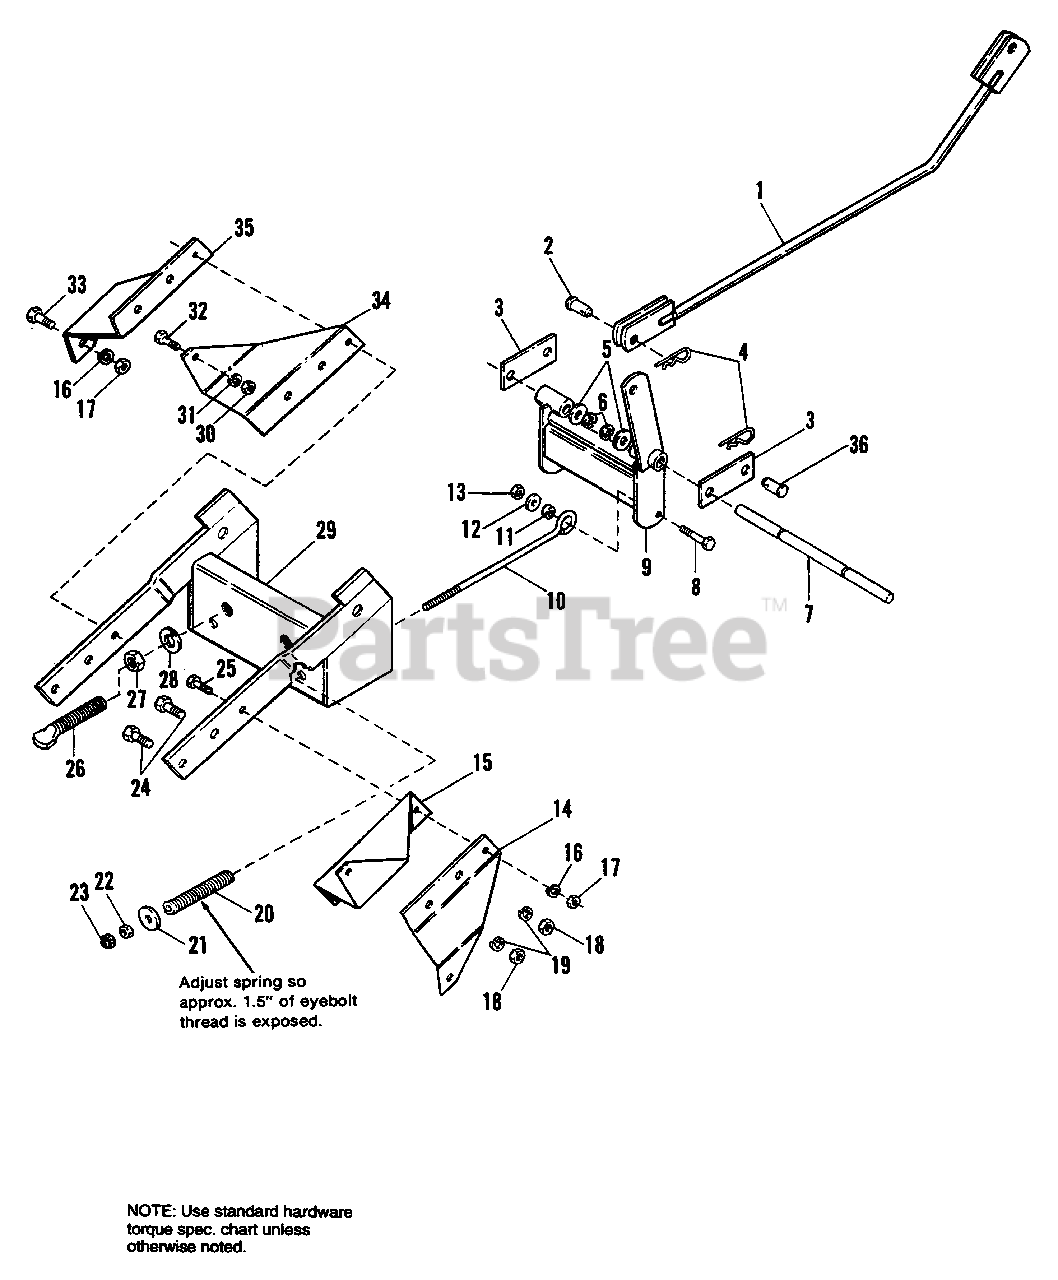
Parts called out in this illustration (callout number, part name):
1	LIFT ROD ASSY.
2	PIN, Clevis
4	CLIP, Hair Pin
5	WASHER, Plain, 41/64 x 1-1/4
6	RING, Retaining, 5/8
7	SHAFT, Inner
8	CAPSCREW, Hex Hd., 5/8-11 x 2
9	HITCH ASSY.
12	WASHER, Plain, 41/64 x 1-3/4
13	NUT, Hex, Centerlock, 5/8-11
14	BRACKET, Attaching, L.H., Lower
15	BRACKET, Attaching, L.H., Upper
16	LOCKWASHER, 3/8
17	NUT, 3/8-16
18	NUT, 7/16-14
19	LOCKWASHER, 7/16
20	SPRING, Compression
21	WASHER, 3/8 x 1-3/4 x 1/4
22	NUT, Hex, 3/8-16
23	NUT, Hex, Jam, 3/8-16
24	CAPSCREW, 7/16-14 x 1-1/4
25	CAPSCREW, 3/8-16 x 1-1/4
27	NUT, Hex, 3/4-10
28	LOCKWASHER, 3/4 Std.
29	HITCH ASSY., Blower
30	NUT, 1/2-13
31	LOCKWASHER, 1/2
32	CAPSCREW, Hex Hd., 1/2-13 x 1
33	CAPSCREW, Hex Hd., 3/8-16 x 1
34	BRACKET, Attaching, R.H., Upper
35	BRACKET, Attaching, R.H., Lower
36	PIN ASSY. (Flat Head)
